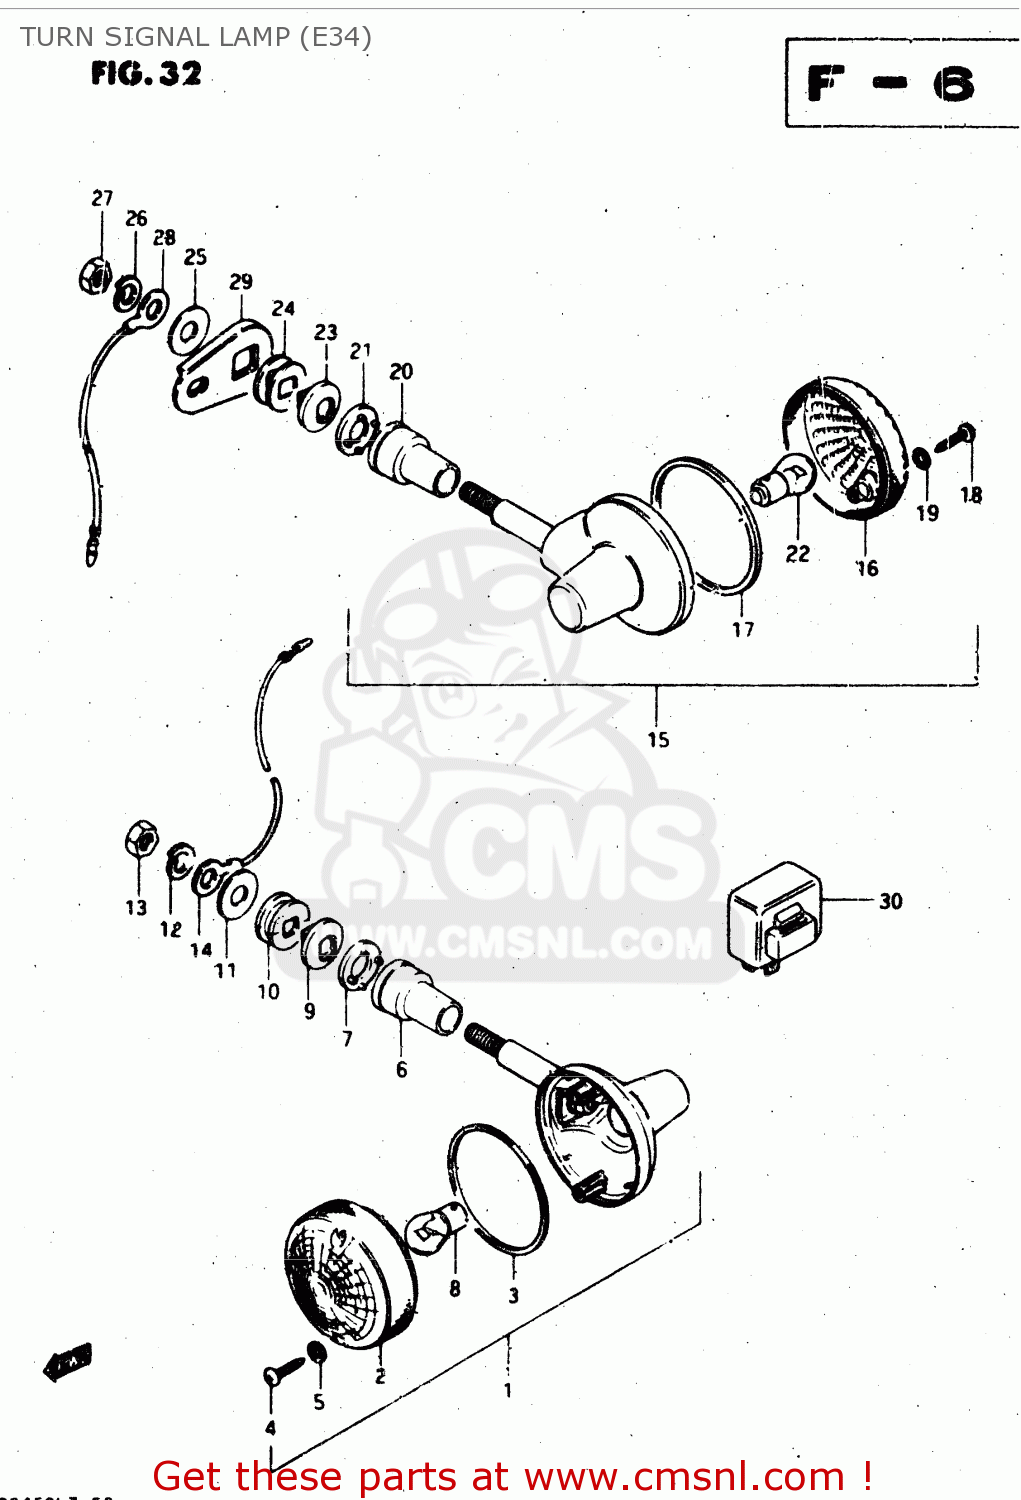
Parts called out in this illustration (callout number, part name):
1	LAMP, REAR TURN SIGNAL
2	LENS
3	GASKET (NAS)
4	SCREW
5	GASKET (NAS)
6	COVER,STAY
7	CUSHION
8	BULB(12V21W)
9	SPACER
10	CUSHION
11	WASHER (10.5X30X2.3)
12	LOCK WASHER
13	NUT
14	LEAD WIRE,EARTH
15	LAMP, REAR TURN SIGNAL
16	LENS,TURN SIGN
17	GASKET (NAS)
18	SCREW
19	GASKET (NAS)
20	COVER,STAY
21	CUSHION
22	BULB(12V21W)
23	SPACER
24	CUSHION
25	WASHER (10.5X30X2.3)
26	LOCK WASHER
27	NUT
28	LEAD WIRE,EARTH
29	BRACKET,RR TURN SIGNAL LAMP
30	RELAY,TURN SIGNAL
